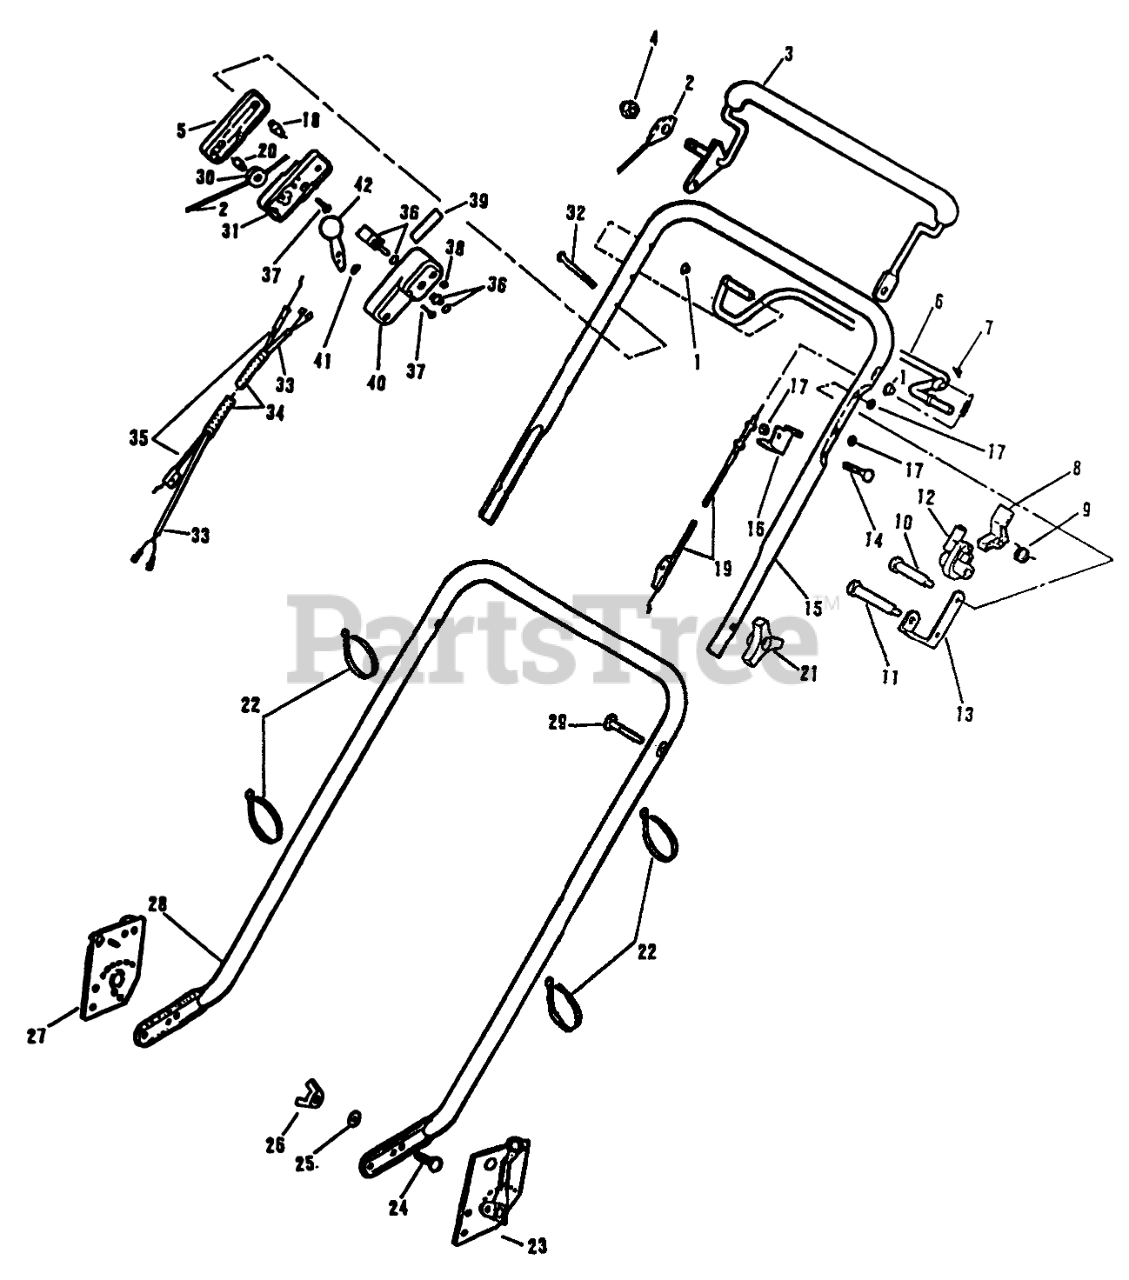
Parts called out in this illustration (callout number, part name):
1	NUT-PUSH
2	CONTROL CABLE WES
3	CONTROL LEVER ARG
4	NUT ACORN
5	OUTER CONTROL CASE
6	C'TROL LEVER ARGO
7	NUT
8	Stop-Latch Lever
9	SPRING ASOC
10	BOLT-SHOULDER
11	BOLT
12	CAM EVCO
13	BRACKET PRINCIPAL
14	SCREW
15	Handle-Top
16	ANCHOR C'DUIT TRO
17	LOCKNUT E
18	COLUMN
19	CABLE - CONTROL
20	PIN SKF
21	Knob
22	TIE-CABLE
23	HEIGHT ADJ AY-LH
24	Bolt
25	WASHER LOCK B'GER
26	NUT WING
27	HEIGHT ADJ AY-RH
28	Handle-Lower
29	Screw
30	PULLEY PL
31	CENTER CONTROL CASE
32	SCREW
33	WIRE HARNESS AY
34	SPIRAL TUBING MMN
35	CABLE TH'TTLE WES
36	SWITCH ASM
37	SCREW
38	NUT C/LOCK E
39	DECAL-THROT CONTRL
40	CASE THROTTLE NLC
41	WASHER-SPRING
42	LEVER&KNOB AY WES
